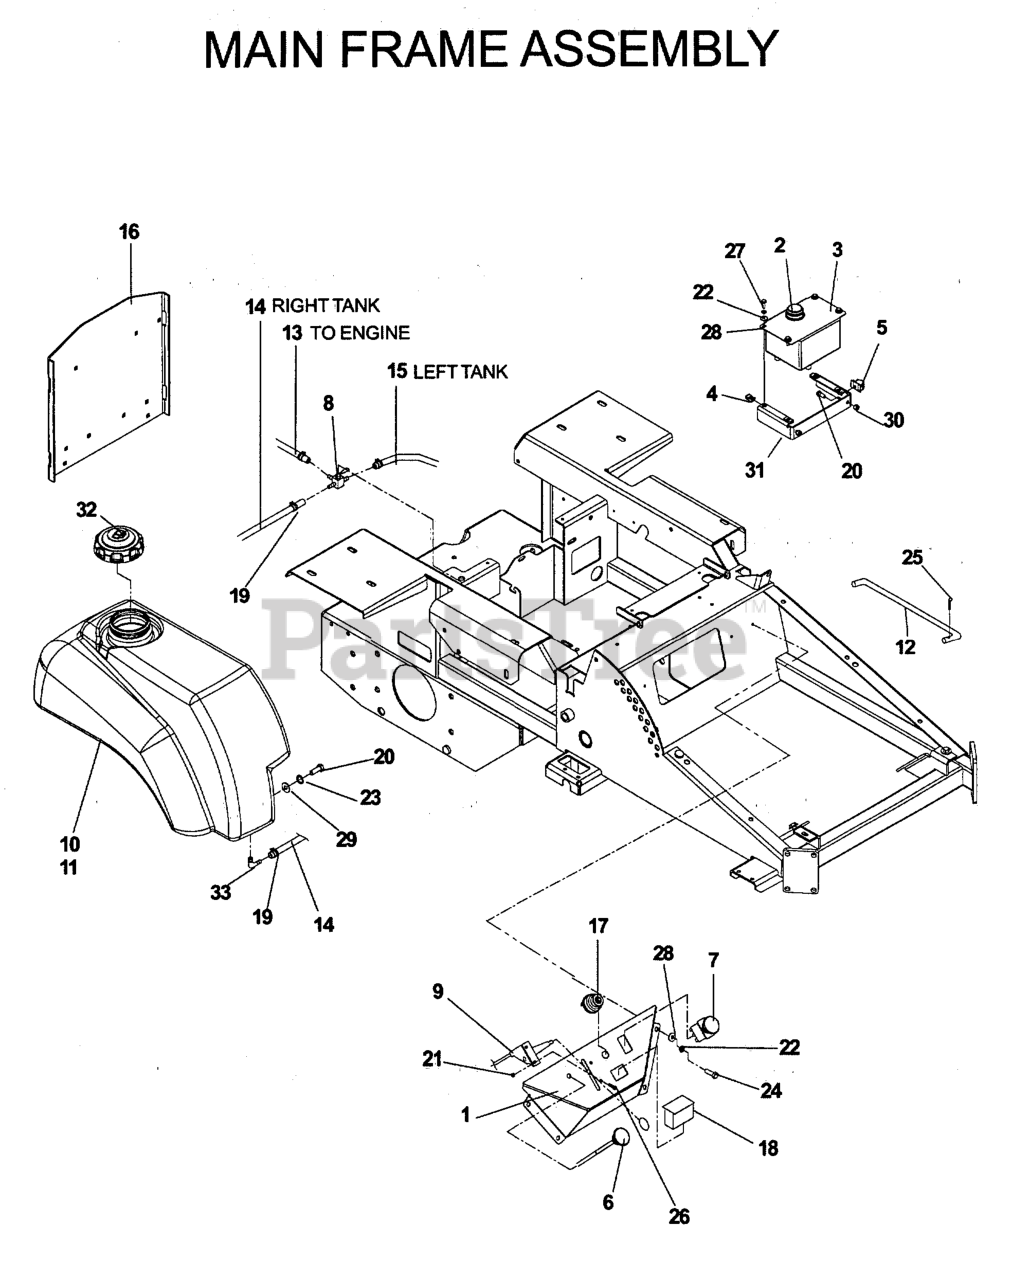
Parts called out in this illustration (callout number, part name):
1	CONSOLE W/DECALS
2	HYDRAULIC CAP
4	1/4C - U TYPE RETAINER
5	PUSH-MOUNT WIRE CLIP
6	CHOKE CONTROL, COMPLETE
7	RP.SWITCH, BLADE
8	FUEL VALVE
9	THROTTLE CABLE
10	LEFT TANK W/CUP HOLDER
11	FUEL TANK RT
13	FUEL LINE 29.5"
14	FUEL LINE 24"
15	FUEL LINE 34"
16	ENGINE GUARD
17	RP IGNITION SWITCH
18	HOUR METER
19	HOSE CLAMP
20	HCS 5/16C X 3/4
21	NUT 10-24 NYLOC
22	LOCKWASHER 1/4"
23	WASHER.LOCK.HVY.HLCL.SPR.5/16
24	SCREW 1/4 X 5/8
25	RP_COTTER PIN 1/8 X 3/4
26	HCS #10-24 X 1/2
27	HCS 1/4C X 3/4 HCS
28	WASHER 1/4 FLAT
29	WASHER 5/16 FLAT
30	NUT 5/16 NYLOC
31	TANK MOUNT
32	FUEL CAP ANTI-SPLASH
33	HOSE BARB 90 DEGREE
